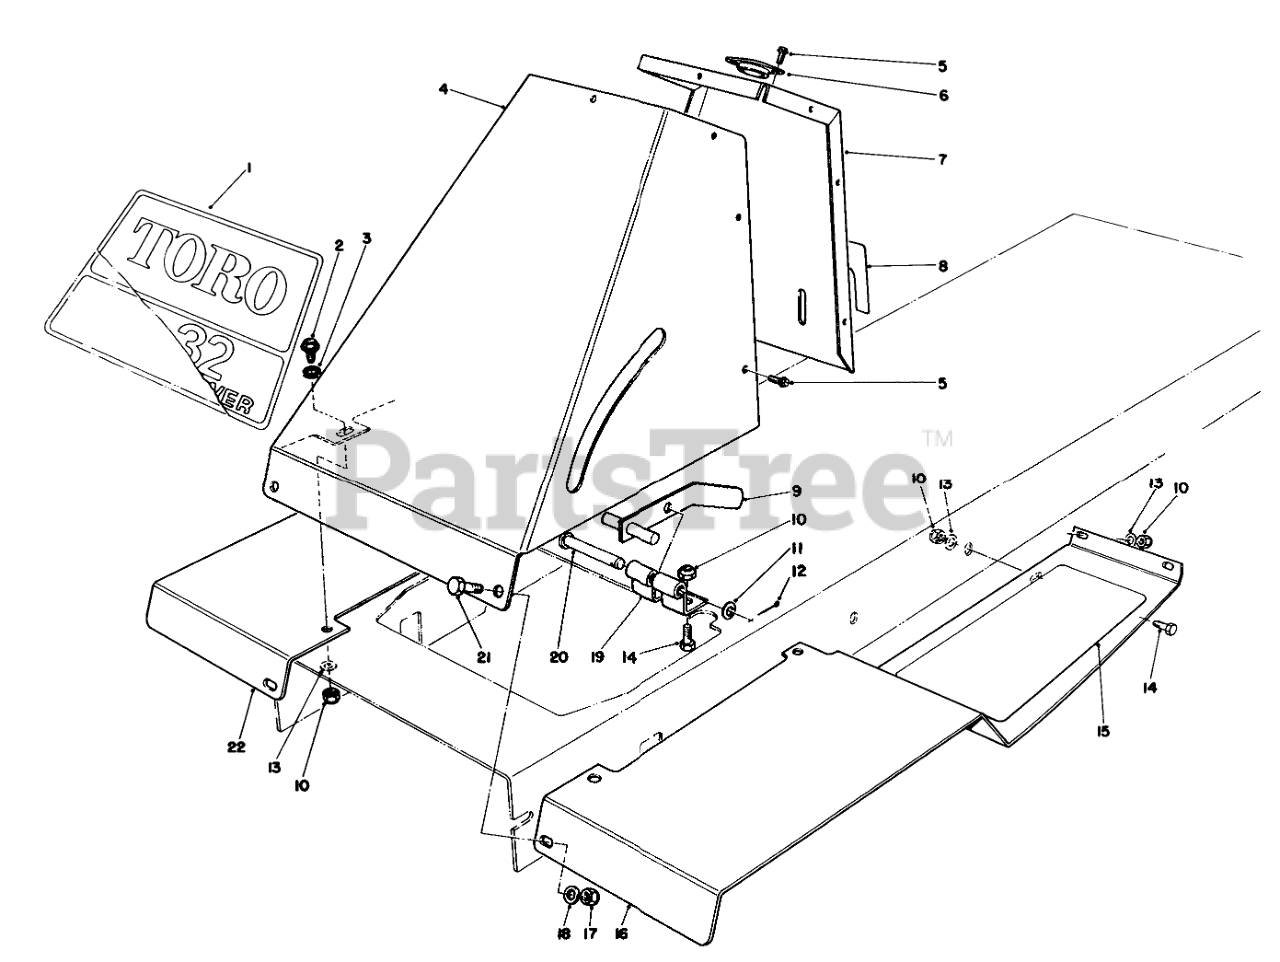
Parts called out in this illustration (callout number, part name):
1	1132 TORO PROF DECAL
2	SCREW-SHOULDER
3	SPACER
4	Tower-Front
5	SCREW-HWHTF
6	GUIDE-STRG SHAFT
7	Tower-Rear
8	PARK BRAKE DECAL
9	PARKING BRAKE WA B
10	NUT-LOCK, NI
11	NUT-LOCK, NI
12	PIN-COTTER
13	WASHER-PLAIN
14	SCREW-HH
15	FOOT TREAD L.H.
16	Footrest-LH
17	NUT-LOCK, CONE
18	WASHER-FLAT
19	Bracket-Parking Brake
20	PIN-CLEVIS
21	SCREW-HH
22	Footrest-RH.
